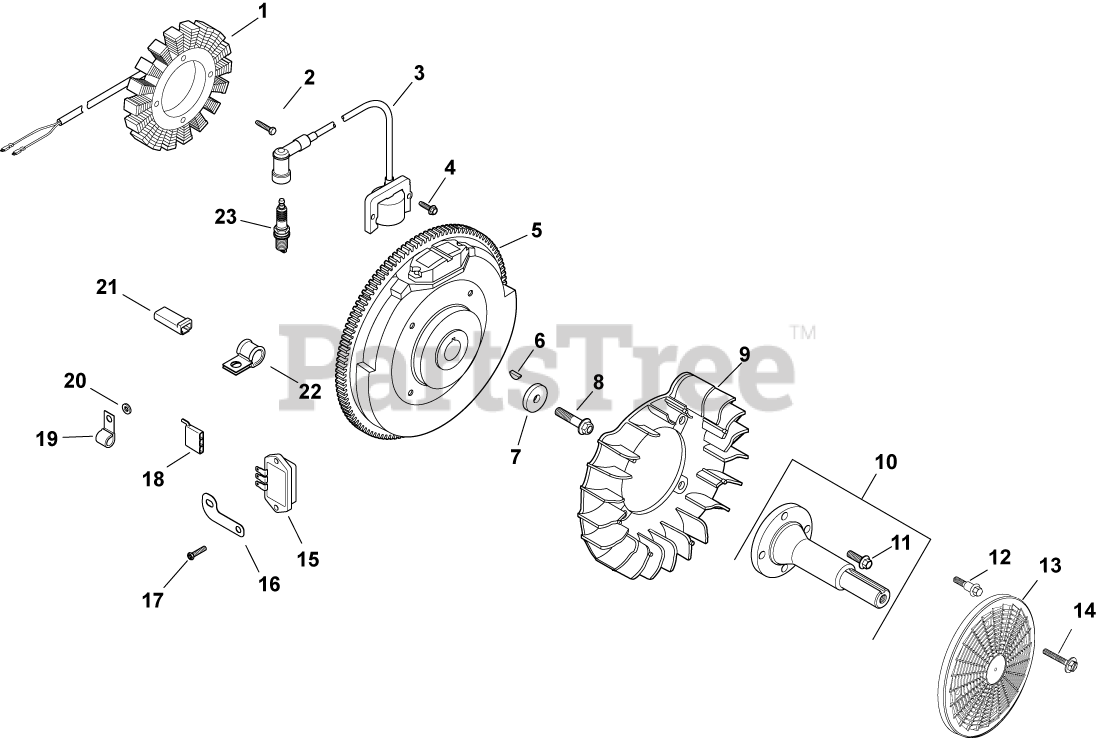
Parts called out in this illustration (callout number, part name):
1	KIT, 15 / 20 AMP STATOR
2	SCREW, M5X0.8X25 - (#25086402S)
3	KIT, MODULE IGNTN (CDI FIXED)
4	SCREW, FLG THD FRM M5X.8X20-(#25086399S)
6	KEY, 3/16" X 5/8"
7	WASHER, FLAT 13/32"
8	SCREW, FLG M10X1.5X45 - (#25086361S)
9	FAN USE 24 755 253-S
10	SHAFT, FRONT DRIVE
11	SCREW, FLG M8X1.25X25
12	BOLT, SHOULDER
13	SCREEN, GRASS-USE 24 162 45-S
14	SCREW, FLG SEMS M4X.7X25
15	REG/RECT-15 AMP (KM)-USE 41 403 10-S
16	BRACKET, GROUND STRAP USE 24 518 12-S
17	SCREW, HEX FLANGE HI-LO
18	CONNECTOR
19	CLIP, CABLE
20	WASHER, FLAT 1/4" (O.D. 1/2")
21	CONNECTOR (1 CONTACT)
23	PLUG, SPARK (STD)
